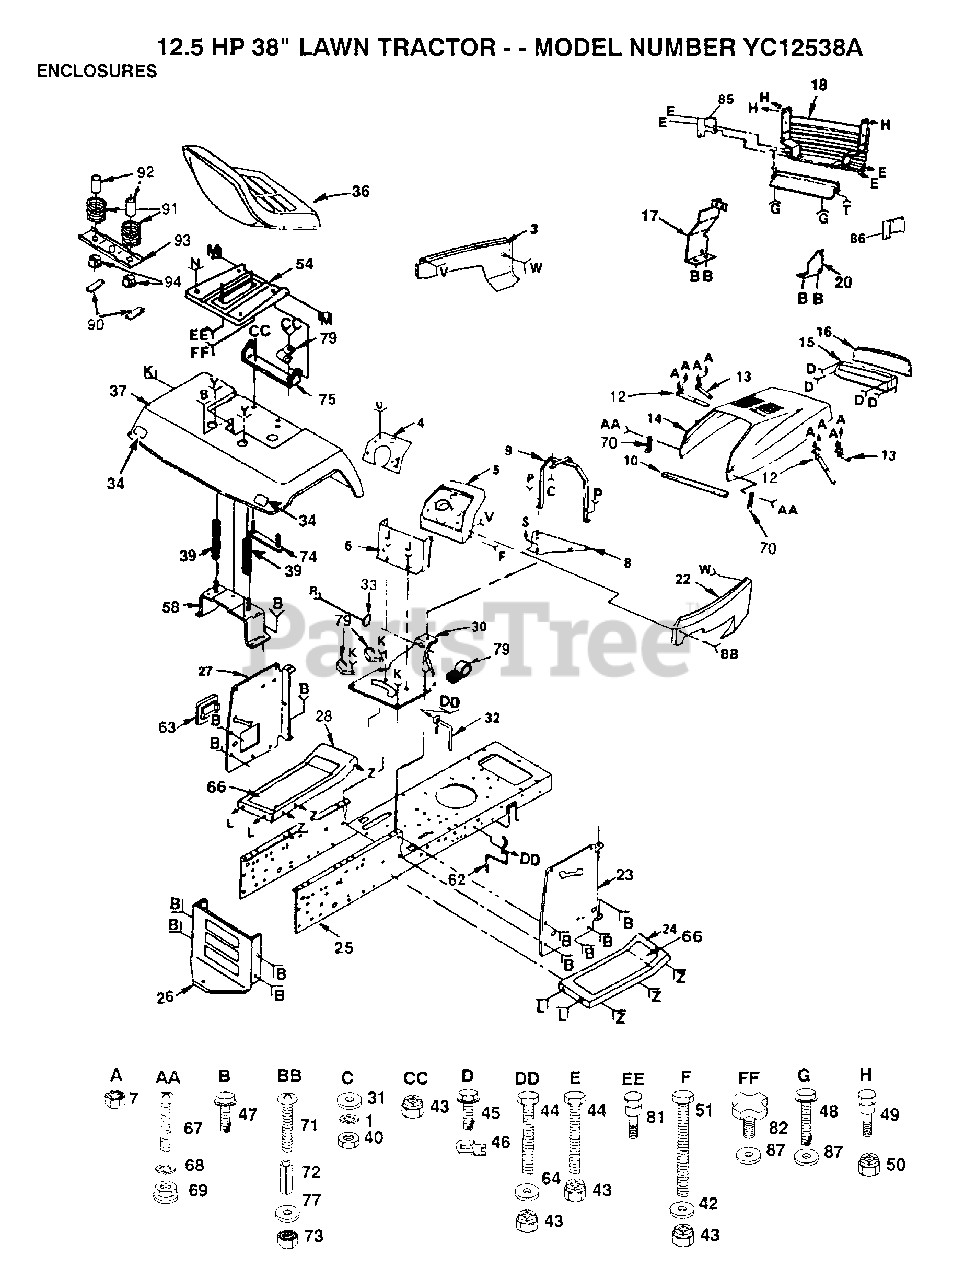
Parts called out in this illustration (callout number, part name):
1	LOCKWASHER
6	DASH ASSY LT
7	NUT
9	SUPPORT ASSY LT
10	FOAM-STRIP LT
16	LENS LT
20	SUPPORT LH YTH
23	PANEL DASH RH YT
31	WASHER PM
32	BELT GUIDE
34	REFLECTOR-TAIL YT
39	SPRING COMPRESSIO
42	WASHER
44	BOLT
46	"""J"" FASTENER LT"
47	SCREW
48	SCREW
62	BELT GUIDE
63	COVER ACCESS
64	WASHER
66	PAD FOOTREST T
67	SCREW
68	LOCKWASHER
69	WELDNUT
70	HOOD LATCH T
71	SCREW
72	SPACER LT
77	WASHER
79	CLIP T
81	"BOLT,SHOULDER"
82	"KNOB 1/2"" YT"
85	SUPPORT LH YTH
86	SUPPORT RH YTH
87	WASHER
90	STRIP FORM
91	SPRING
92	SPACER SPLIT
93	BRKT SWITCH
94	BUSHING
